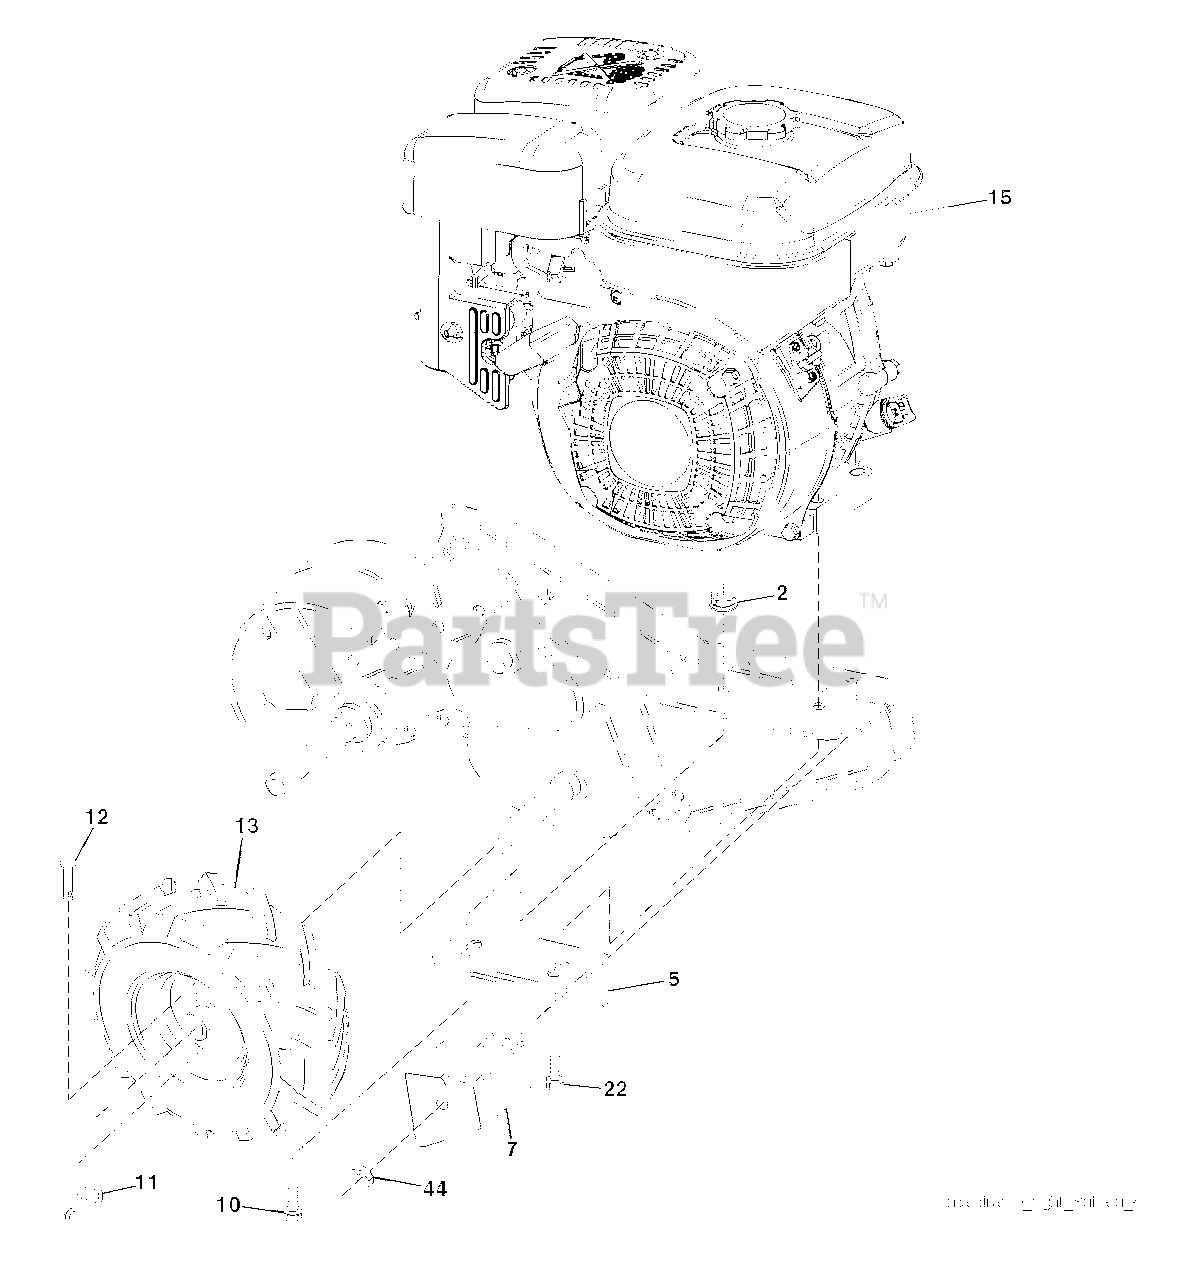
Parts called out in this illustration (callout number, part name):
2	LOCKNUT-FLANGE 5/16-18
5	BRACKET RH CRT
7	COUNTERWEIGHT, RH
10	BOLT
12	RIVET,DRILLED
13	TIRE.16X4-8.CHEVRON.TILLER
22	BOLT, HEX 5/16-18X1-3/4
